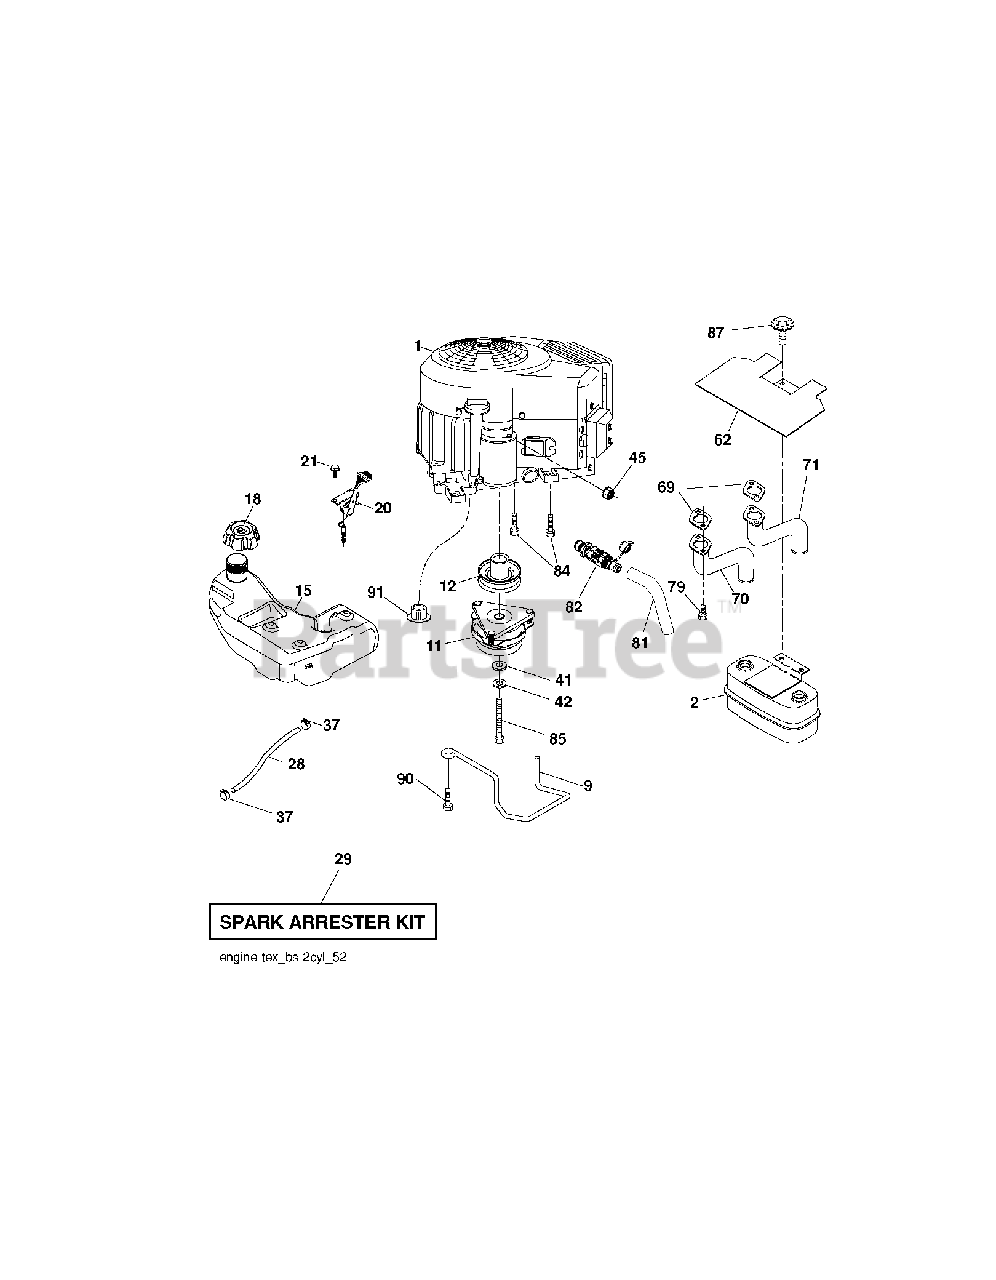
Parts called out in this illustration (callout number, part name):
2	MUFFLER.TWIN.CYL.LOW.TONE
9	KEEPER.BELT.ENGINE.4.2
11	CLUTCH.ELECTRIC.LT.48"*
12	PULLEY.ENGINE.TUFFTORQ
15	TANK.ASSY.3.GAL.EPA
18	CAP.ASM.FL.RITCH.3"E10.SYM.498
20	CONTROL.TH/CK.COBRA.B&S.TWN.
21	SCREW.#10 X 0.750.BOS
28	LINE.FUEL.64"REAR.EMIS
29	KIT.SPARK ARRESTOR 794945 B&S
37	HOSE CLAMP
42	LOCKWASHER
45	NUT
62	SHIELD.HEAT.MUFFLER
69	GASKET.MUFFLER
70	RP.EXHAUST.TUBE.LH.BS/TWIN
71	EXHAUST.TUBE.RH.BS/TWIN
79	SCREW.SOCKET.HEAD.5/16-18
81	TUBE, DRAIN OIL ASM.
82	VALUE.OIL.DRAIN
84	SCREW.3/8-16
85	BOLT HEX 7/16-20X4-1/4"
87	BOLT, 5/16-18 X 1 3/4
90	SCREW 3/8-16X1
91	BUSHING.1.375OD
